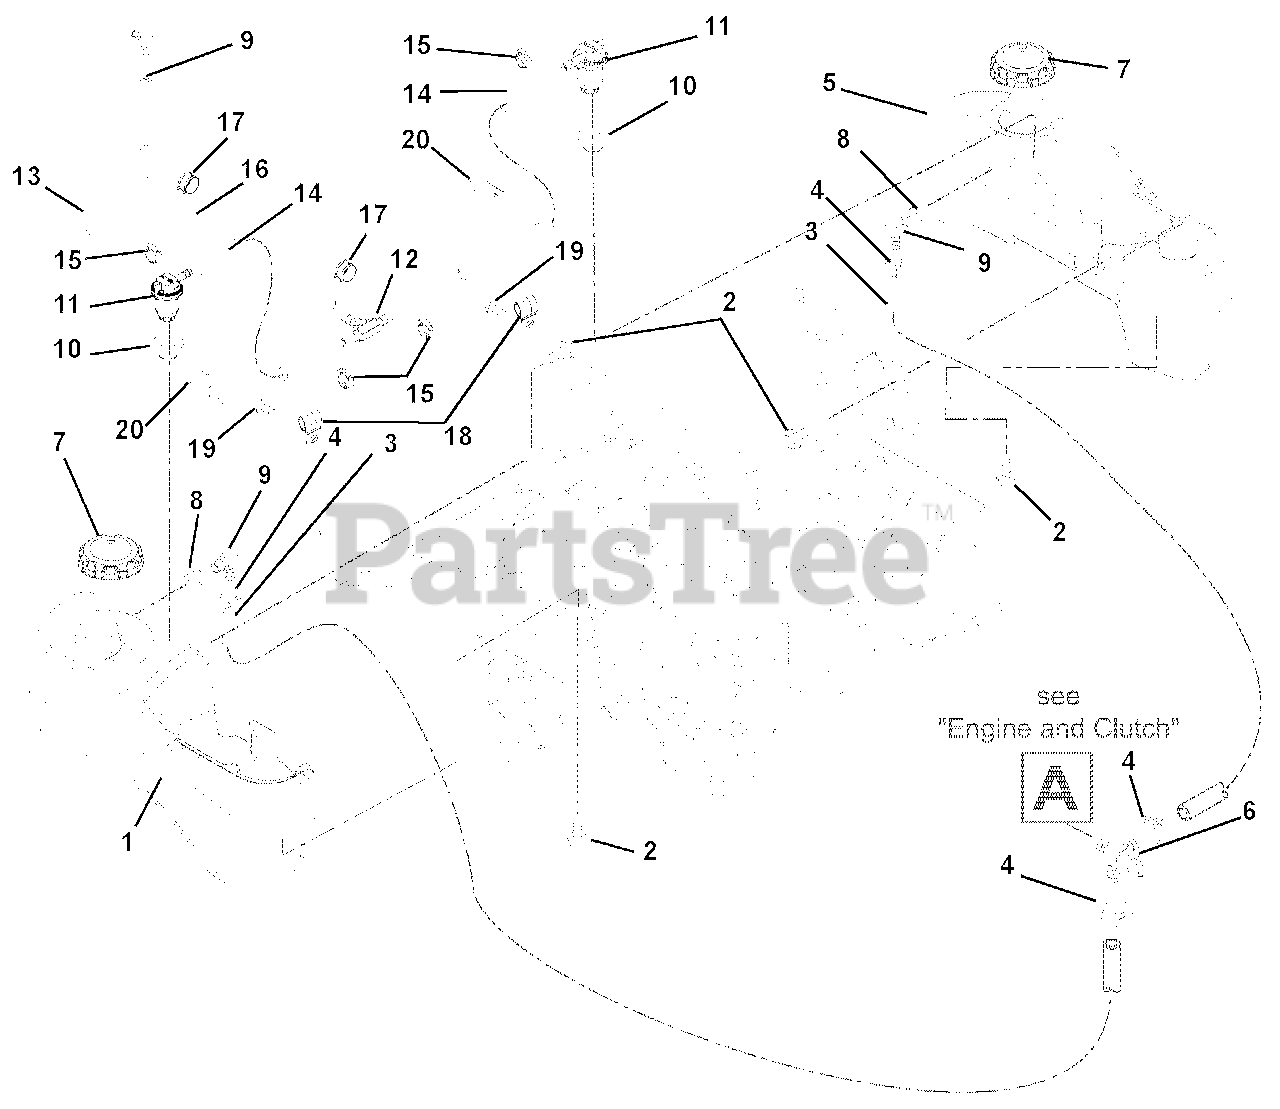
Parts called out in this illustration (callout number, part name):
1	Tank, Fuel - Right Hand
2	Bolt, SEMS .31-18 x .62
3	Hose, .25 Low-PERM Bulk Gas (3 @ 42 in.)
4	Clamp, Fuel Line
5	Tank, Left Hand Fuel
6	Valve, Fuel
7	Cap, Vent-in Ratchet Fuel
9	Assembly, Large Tank Fuel Pick-up
10	Grommet, Remote Vent Nitrile
11	Valve, Combination
12	Fuel Tee, .25 HS Run x .18 HS Branch
14	Hose, .25 Low-PERM Bulk Gas
15	Clamp, Fuel Line
16	Hose, .188 Low-PERM Bulk Gas
17	Clamp, Hose Spring .188
18	Clamp, Cushioned Steel
19	Screw-Tapping .31-18 x .50 Hex Washer Head Thread Rolling
